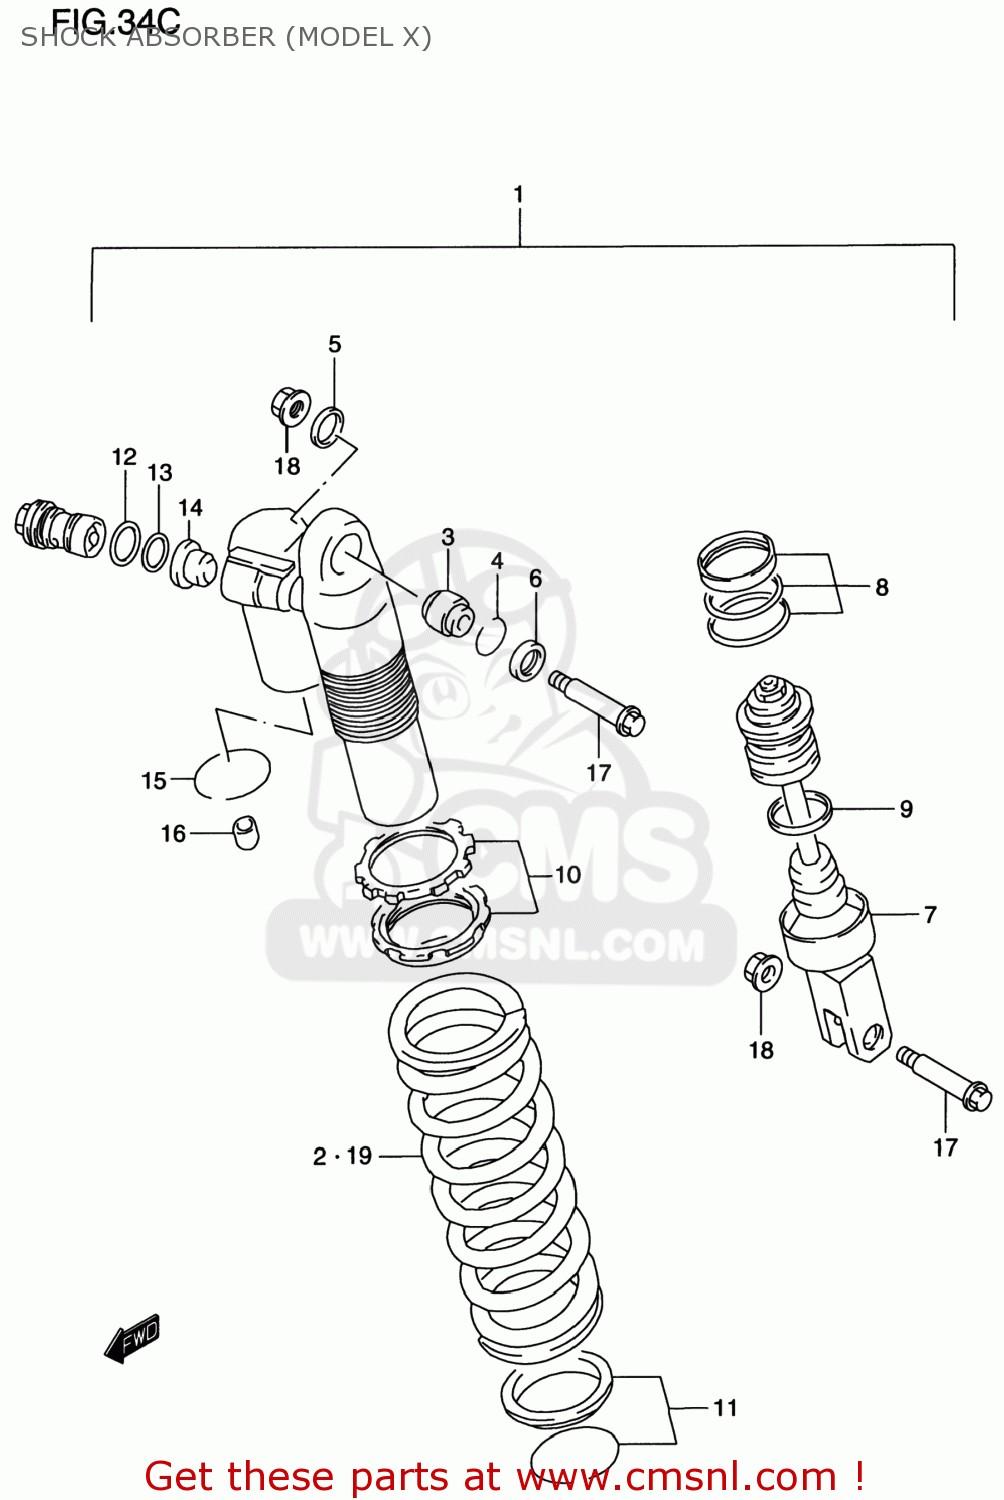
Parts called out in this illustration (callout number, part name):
1	ABSORBER ASSY,RR SHOCK
2	SPRING,RR(K=4.7X5.32X6.14)
3	BEARING,RR SHOCK ABSORBER
4	RING,STOPPER
5	SEAL,DUST UPR,R
6	SEAL,DUST UPR,L
7	ROD,PISTON
8	O RING SET
9	RING,STOPPER
10	ADJUSTER SET
11	SPRING SEAT SET
12	O RING
13	O RING,CTR BOLT UPR
14	COLLAR
15	RING,STOPPER
16	CAP
17	BOLT(10X47.5)
18	NUT
19	SPRING,REAR (K=4.5X5.1)
